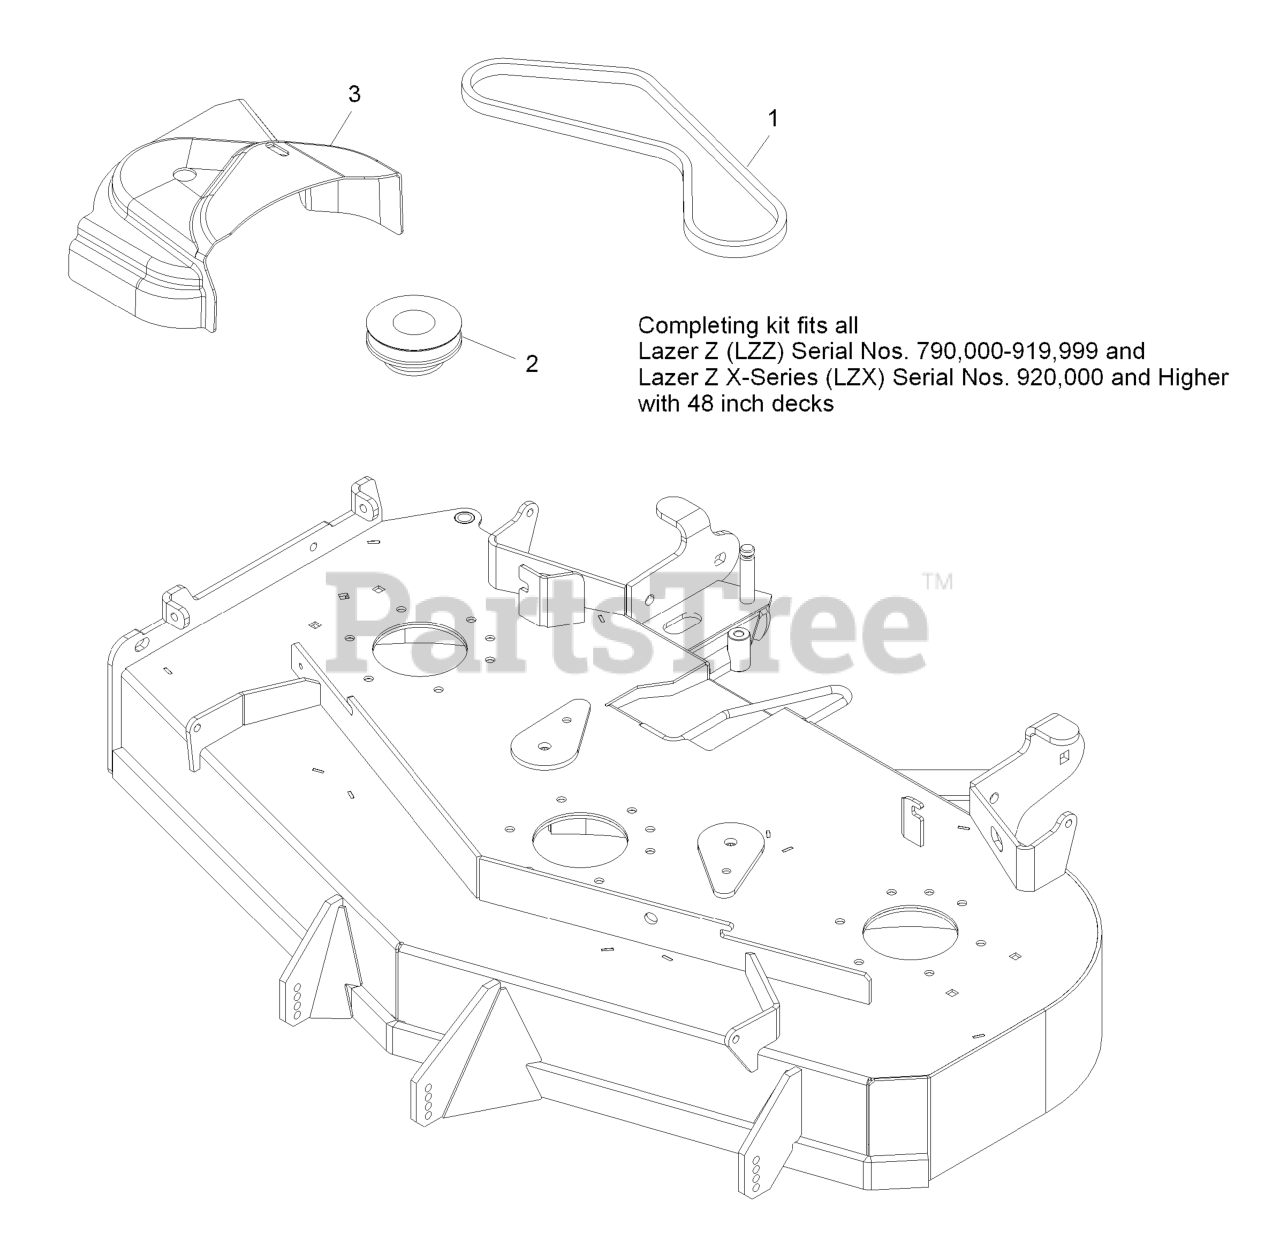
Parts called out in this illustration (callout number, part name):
1	BELT-BLOWER
2	SHEAVE,DRIVE LZUV 486
3	COVER,BELT UV 48
